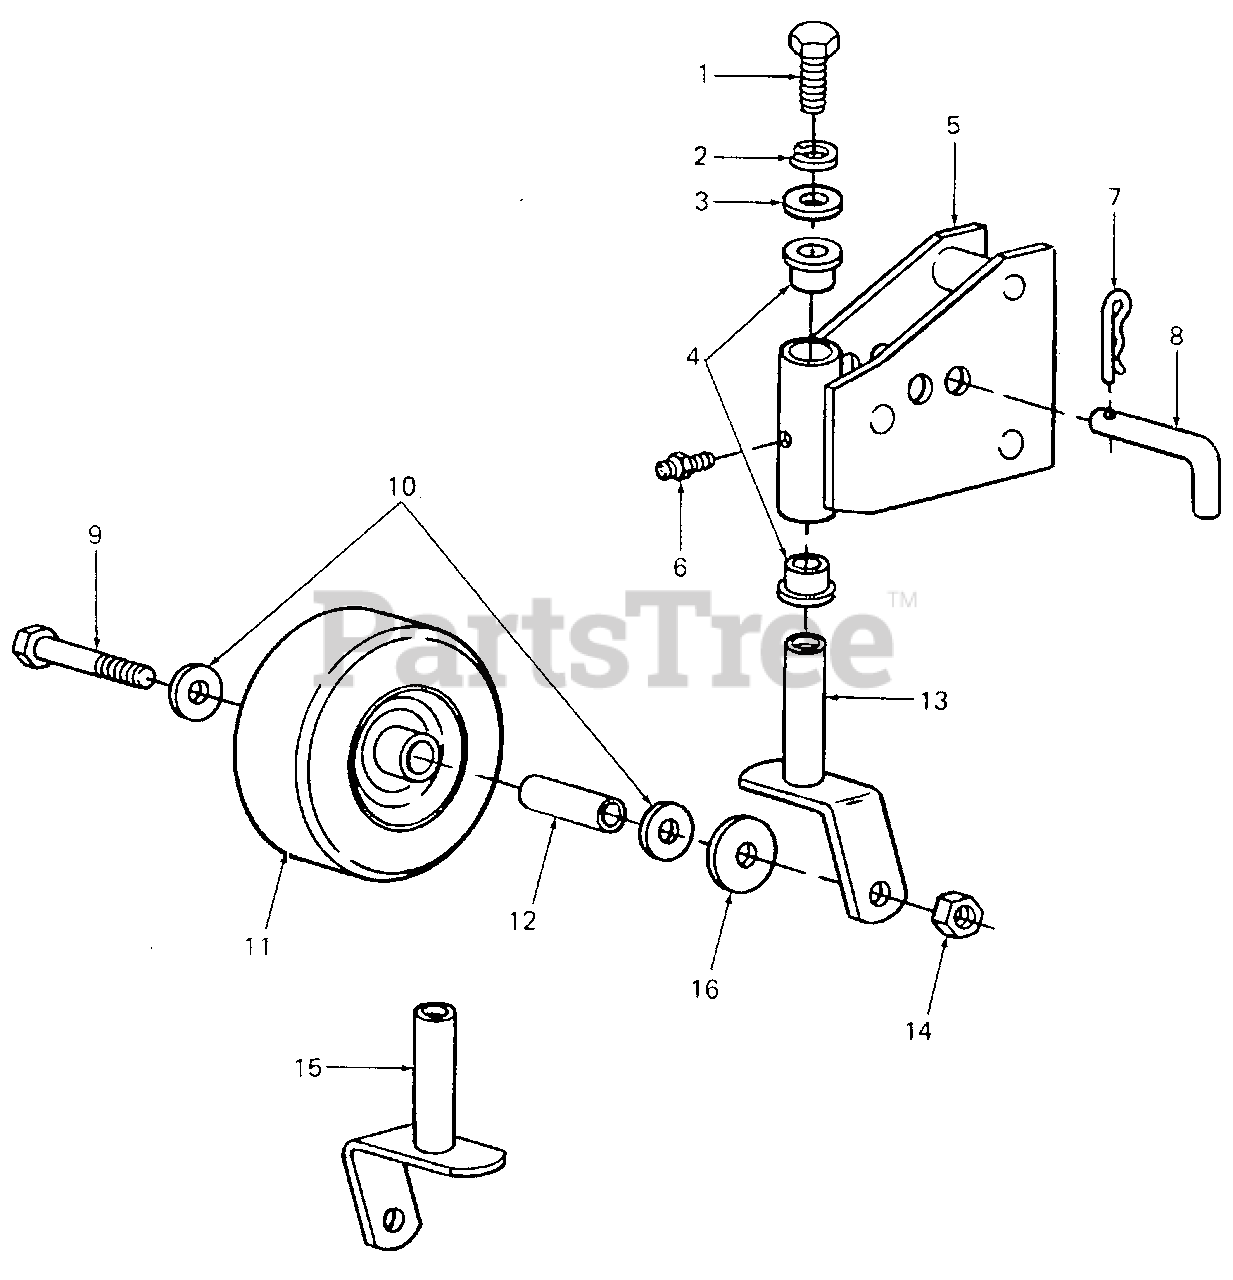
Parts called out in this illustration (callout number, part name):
1	Screw, Hex Cap, 3/8-16 X .75 Lg GR5
2	Washer, Lock, 3/8
3	Washer, Flat, .438 ID X 1.00 OD X .064 Thk
4	Bushing, Flange
5	Mounting Assy, Front Caster
6	Fitting, Grease
7	Pin, Quick Attach
8	Pin, Front Wheel Axle
9	Screw, Hex Cap, 1/2-13 X 4.0 Lg GR5
10	Washer, Flat, .562 ID X 1.375 OD X .109 Thk
11	Wheel, Front Gauge, 6"
12	Spacer, Wheel
